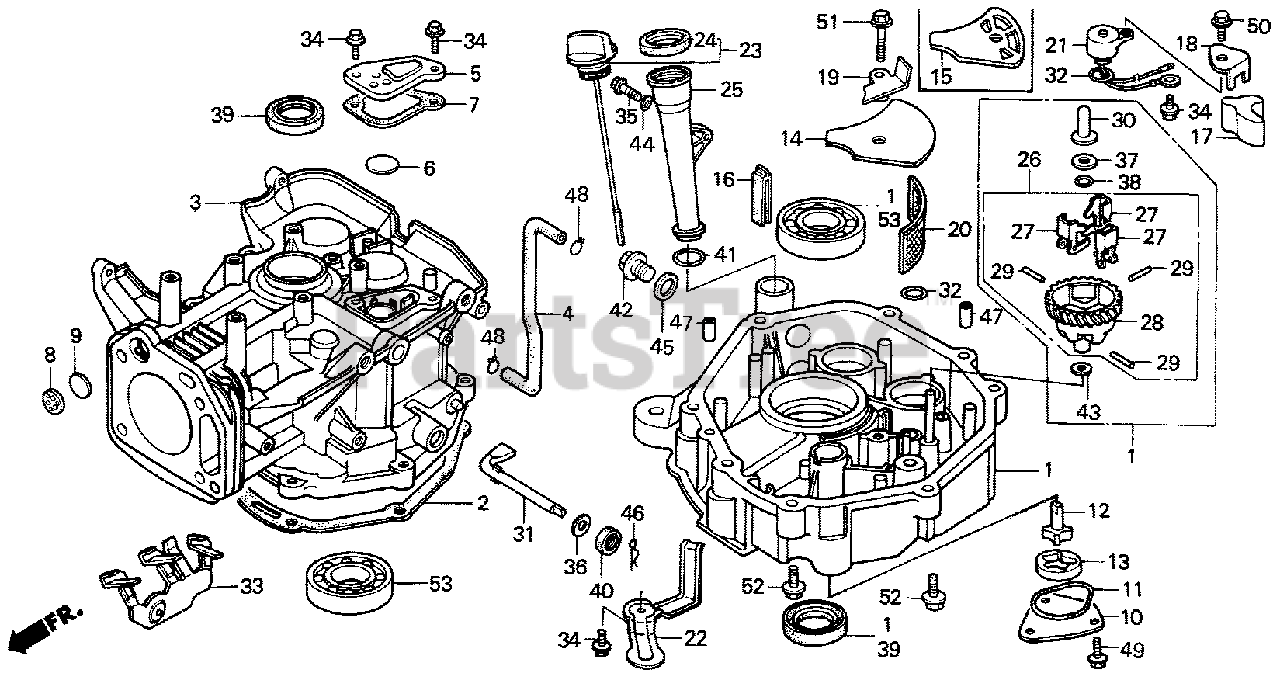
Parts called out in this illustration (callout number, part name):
1	PAN ASSY., OIL
2	GASKET, OIL PAN
3	CYLINDER
4	TUBE, BREATHER
5	CAP, BREATHER CHAMBER
6	VALVE, BREATHER
7	GASKET, BREATHER CAP
8	PLATE, ONE-WAY VALVE
9	VALVE, ONE-WAY
10	COVER, OIL PUMP
11	O-RING, PUMP COVER
12	ROTOR (INNER)
13	ROTOR, OIL PUMP (OUTER)
15	PLATE, OIL FILTER
16	RUBBER, OIL RETURN
17	STOPPER, OIL
18	PLATE, OIL STOPPER
19	PLATE, SUCTION
20	SCREEN, OIL FILTER
21	SWITCH, OIL LEVEL
22	PROTECTOR, SWITCH
23	CAP ASSY., OIL FILLER
24	GASKET, OIL FILLER CAP
25	EXTENSION, OIL FILLER
26	GOVERNOR ASSY.
27	WEIGHT, GOVERNOR
28	HOLDER, GOVERNOR WEIGHT
29	PIN, GOVERNOR WEIGHT
30	SLIDER, GOVERNOR
31	SHAFT, GOVERNOR ARM
32	O-RING (11.8X2.4)
33	STAY, SWITCH WIRE CLAMP
34	BOLT, FLANGE (6X12) (CT200)
35	BOLT, FLANGE (6X35)
36	WASHER, THRUST (8.1MM)
37	WASHER (6X16)
38	CLIP, GOVERNOR HOLDER
39	OIL SEAL (30X46X8)
40	OIL SEAL (8X14X5)
41	O-RING (22.5X2.2)
42	BOLT, DRAIN PLUG (20MM)
43	WASHER, PLAIN (6MM)
44	WASHER, PLAIN (6MM)
45	WASHER, DRAIN PLUG (20MM)
46	PIN, LOCK (8MM)
47	PIN A, DOWEL (8X14)
48	CLIP, TUBE (C11)
49	BOLT, FLANGE (6X12)
50	BOLT, FLANGE (6X16)
51	BOLT, FLANGE (6X25)
52	BOLT, FLANGE (8X40)
53	BEARING, RADIAL BALL (6206)
NI	GOVERNOR KIT
